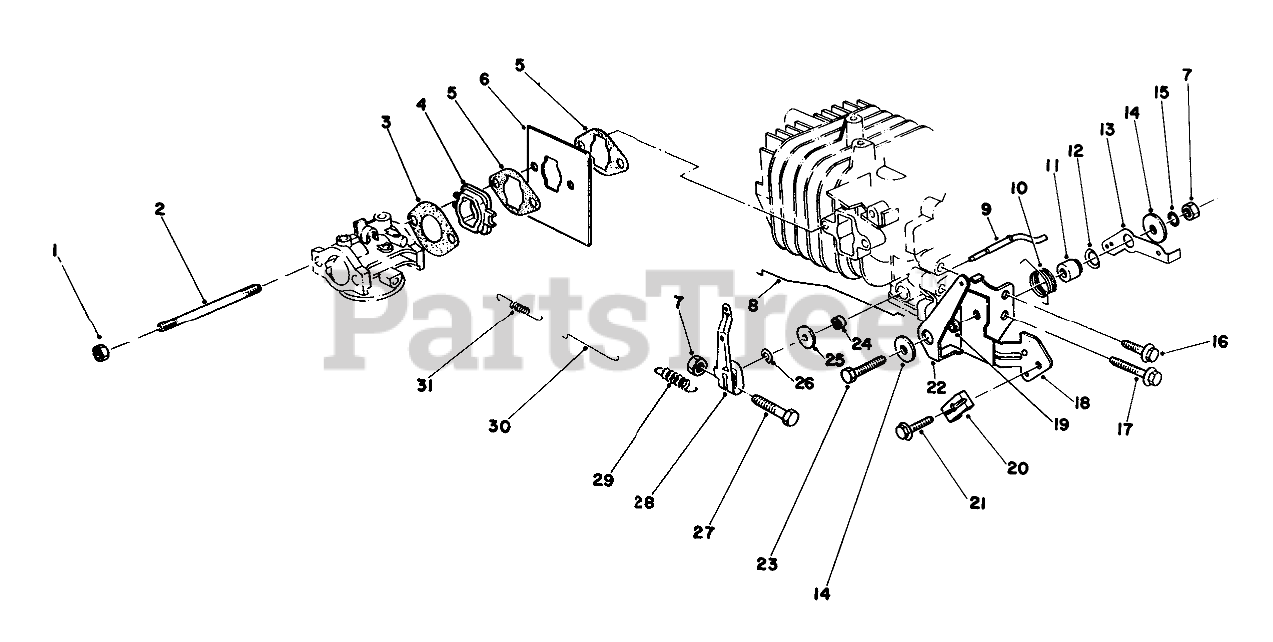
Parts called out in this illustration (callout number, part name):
1	NUT-LOCK
2	CARB STUD BOLT
3	GASKET-CARB
4	INSULATOR
5	GASKET
6	SHIELD
8	CHOKE ROD
9	Shaft-Govemor
10	Spring-Choke Control Lever
11	Gov Lever Spacer
12	Washer-Gov. Spring Lever
13	GOV SPRING LEVER
14	WASHER
15	LOCKWASHER
18	Bracket-Throttle Control
19	Spacer-Choke Control Lever
20	CLAMP-CABLE
22	LEVER-CONTROL, CHOKE
24	SEAL-OIL
25	WASHER
26	E-RING
28	Lever-Throttle Control
29	GOVERNOR SPRING
30	ROD-CARBURETOR
31	SPRING
